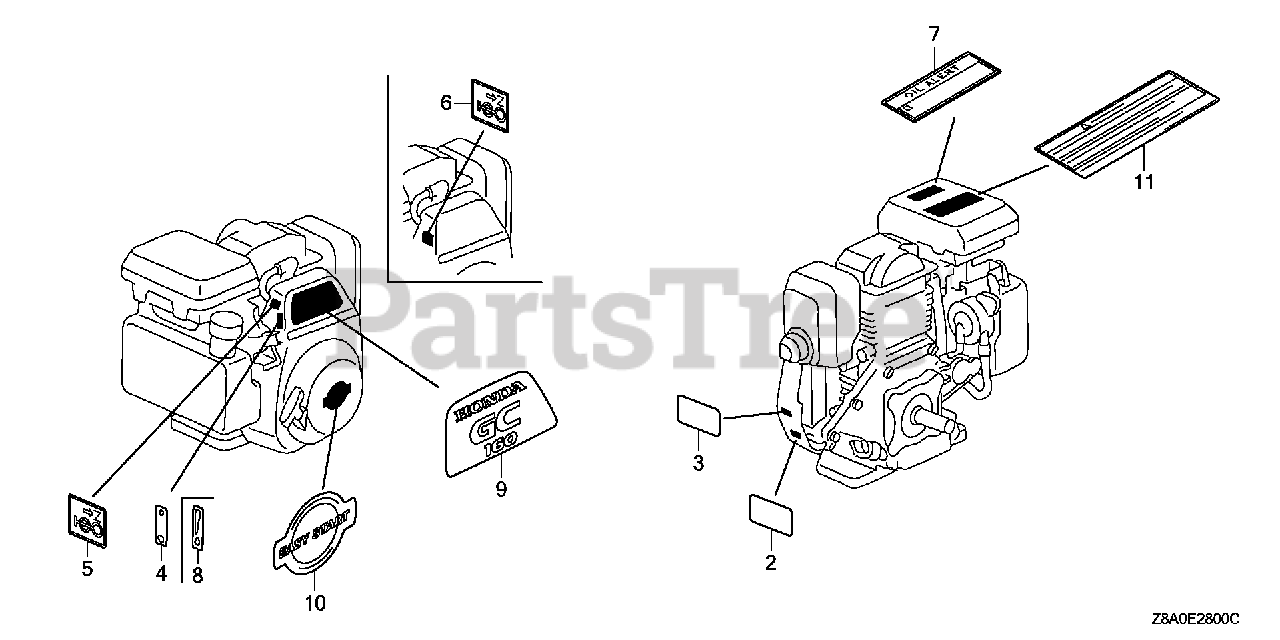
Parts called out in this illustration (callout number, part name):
2	LABEL, WARNING (NOT CERTIFIED FOR SALE)
5	MARK, CHOKE
8	MARK, THROTTLE INDICATION
9	EMBLEM (GC160)
10	MARK, RECOIL COVER
11	MARK, OPERATOR CAUTION (ENGLISH)
11	MARK, OPERATOR CAUTION (CHINA)
